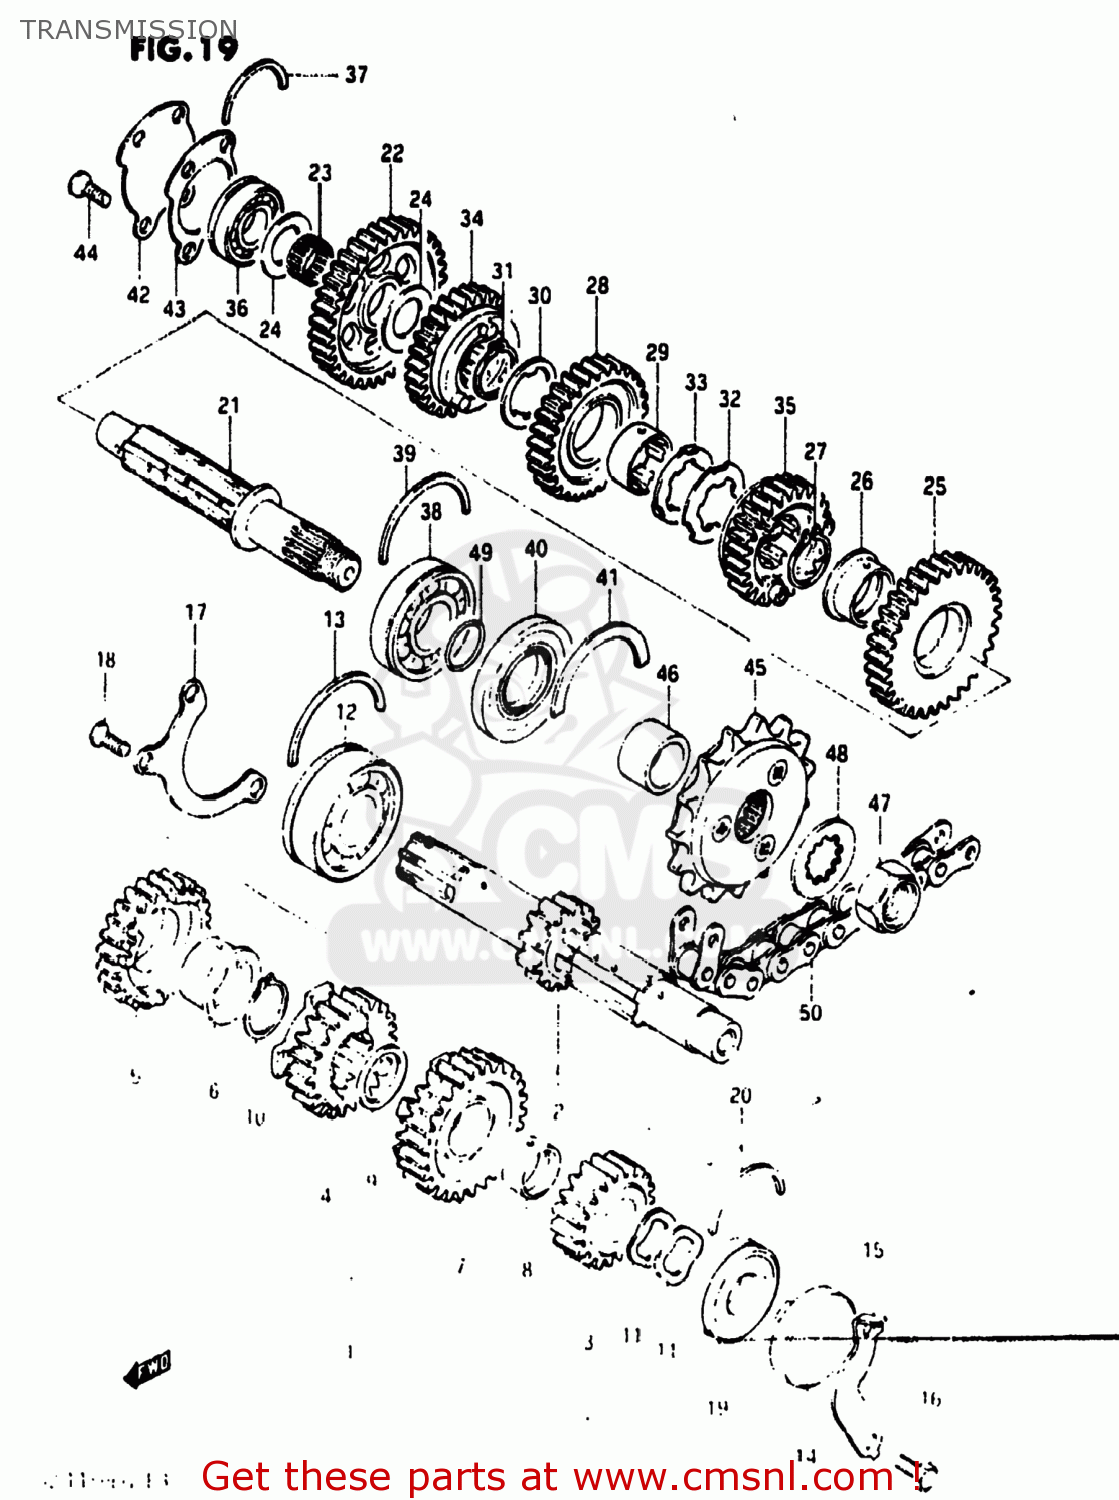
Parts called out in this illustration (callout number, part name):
1	SHAFT,COUNTER
2	SHAFT,COUNTER
3	GEAR,2ND DRIVE(NT:18)
4	GEAR,3RD DRIVE(NT:21)
5	GEAR,4TH DRIVE(NT:24)
6	BUSH(28X32X2)
7	GEAR,5TH DRIVE(NT:26)
8	BUSHING
9	WASHER
10	CIRCLIP
11	WASHER
12	BEARING(25X62X17)
13	C-RING
14	PLUG
15	RETAINER,CL PUSH ROD OIL SEAL
16	BOLT
17	RETAINER,CNTR SHAFT BEARING
18	SCREW
19	BEARING(20X47X14)
20	C RING
21	SHAFT,DRIVE
22	GEAR,FIRST DRIVEN (NT:35)
23	BEARING(20X24X10).8
24	WASHER
25	GEAR,2ND DRIVEN(NT:32)
26	BUSH(28X32X2)
27	CIRCLIP
28	GEAR,THIRD DRIVEN
29	BUSH,3RD DRIVEN GEAR
30	WASHER,LOCK
31	CIRCLIP
32	WASHER,LOCK
33	WASHER
34	GEAR,4TH DRIVEN(NT:27)
35	GEAR,5TH DRIVEN(NT:25)
36	BEARING
37	C RING
38	BEARING
39	C-RING
40	SEAL,OIL(32X62X5)
41	C RING
42	PLATE,DRIVE SHAFT
43	GASKET,DRIVESHAFT PLATE (MCA)
44	SCREW
45	SPROCKET,ENGINE
46	SPACER (25X32X21.6)
47	NUT
48	WASHER
49	O RING(D:1,ID:24.5)
50	CHAIN ASSEMBLY,DRIVE
